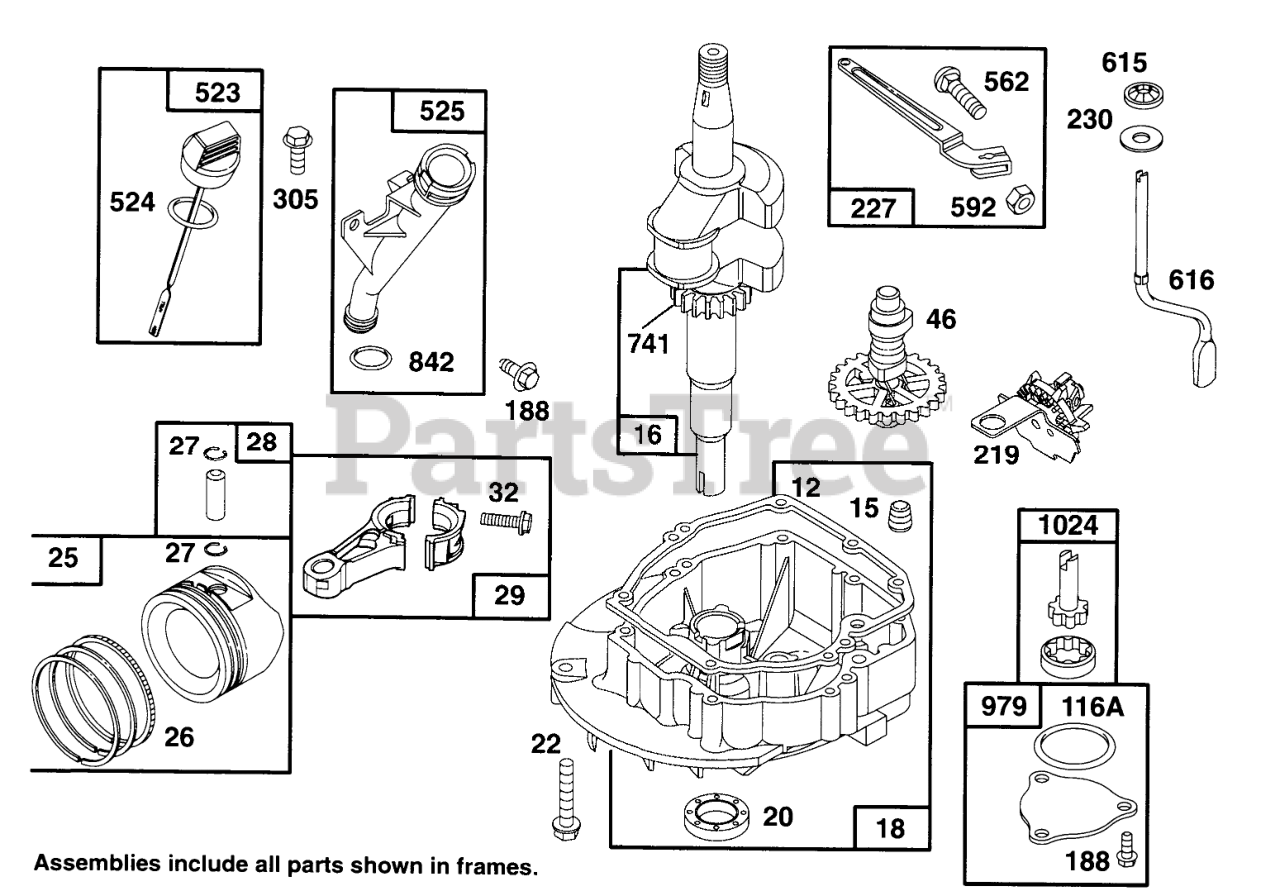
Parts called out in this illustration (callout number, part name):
12	ENGINE BASE GASKET
15	PIPE PLUG
16	Crankshaft
18	ENGINE SUMP
20	SEAL-OIL
22	SCREW - ENGINE BASE
25	STD PISTON ASSEMBLY
26	STD RING SET
27	PISTON PIN LOCK
28	PIN ASM - PISTON
29	CONNECTING ROD
32	SCREW - CONNECTING ROD
46	CAM GEAR
116A	O RING SEAL
188	Screw-Cap
219	GOVERNOR/OIL SLINGER
227	GOVERNOR LEVER ASSEMBLY
230	WASHER
305	SCREW - HEX HEAD
523	DIPSTICK-OIL
524	O-RING
525	OIL FILLER TUBE
562	GOVERNOR LEVER BOLT
592	HEX NUT
615	FASTENER
616	GOVERNOR CRANK
741	TIMING GEAR
842	O-RING
979	OIL PUMP COVER
1024	OIL PUMP
